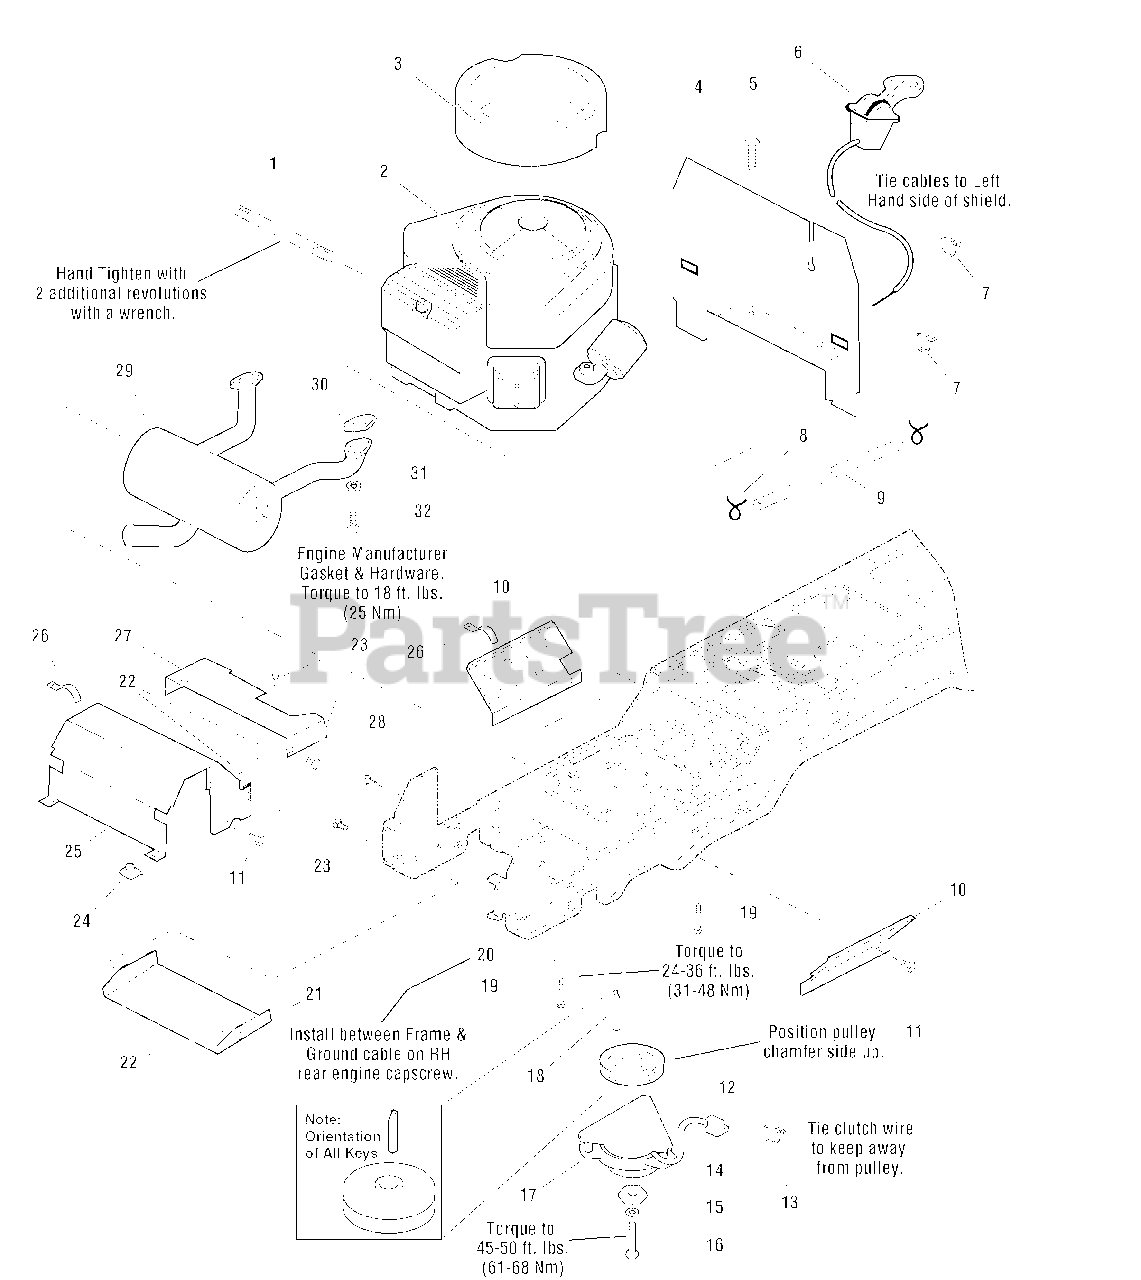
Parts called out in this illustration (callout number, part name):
1	HOSE, Oil Drain, 10-1/2" Long, 3/8-18 Fittings
3	SEAL, Circle, 18HP & 20HP
4	BULKHEAD
5	CAPSCREW, Hex Washer Head Taptite, 1/2-20 x 1/2, Black
6	CONTROL, Throttle Double 39" Long w/Knobs
7	TIE, Wire, 7-5/16" Long
8	CLAMP, Hose Type E
9	HOSE, Fuel, 59" Long
10	SHIELD, Side
11	CAPSCREW, Hex Washer Head Taptite, 1/4-20 x 3/8
12	PULLEY & HUB ASSEMBLY
13	TIE, Self Locking, 3-5/8 Long
14	WASHER, Hex, 7/16, Black
15	LOCKWASHER, 7/16
16	CAPSCREW, Hex Head, 7/16-20 x 3-1/2, 20HP
16	CAPSCREW, Hex Head, 7/16-20 x 2-3/4, 20HP
17	CLUTCH, Electric, 18HP
17	CLUTCH, Electric, 20HP
18	KEY, HI PRO, 1/4 x 2 1/2
19	CAPSCREW, Hex Washer Head Taptite, 3/8-16 x 1-1/2
20	LOCKWASHER, External Tooth, 3/8
21	SHIELD, Muffler Bottom
22	NUT, Speed, 1/4-20, Lug
23	CAPSCREW, Hex Flange Whiz Lock, 1/4-20 x 5/8
24	NUT, Speed, 5/16-18, Lug, Black
25	DUCT, Muffler Top
26	CLIP, Wire 1/8
27	DUCT, Muffler Extension
28	CAPSCREW, Hex Washer Head Taptite, 5/16-18 x 1/2, Black
29	MUFFLER, Briggs & Stratton, Vanguard Twin
30	GASKET, Briggs & Stratton, Vanguard Twin
31	LOCKWASHER, 5/16
32	CAPSCREW, Hex Flange Whiz Lock, 5/16-18 x 7/8
